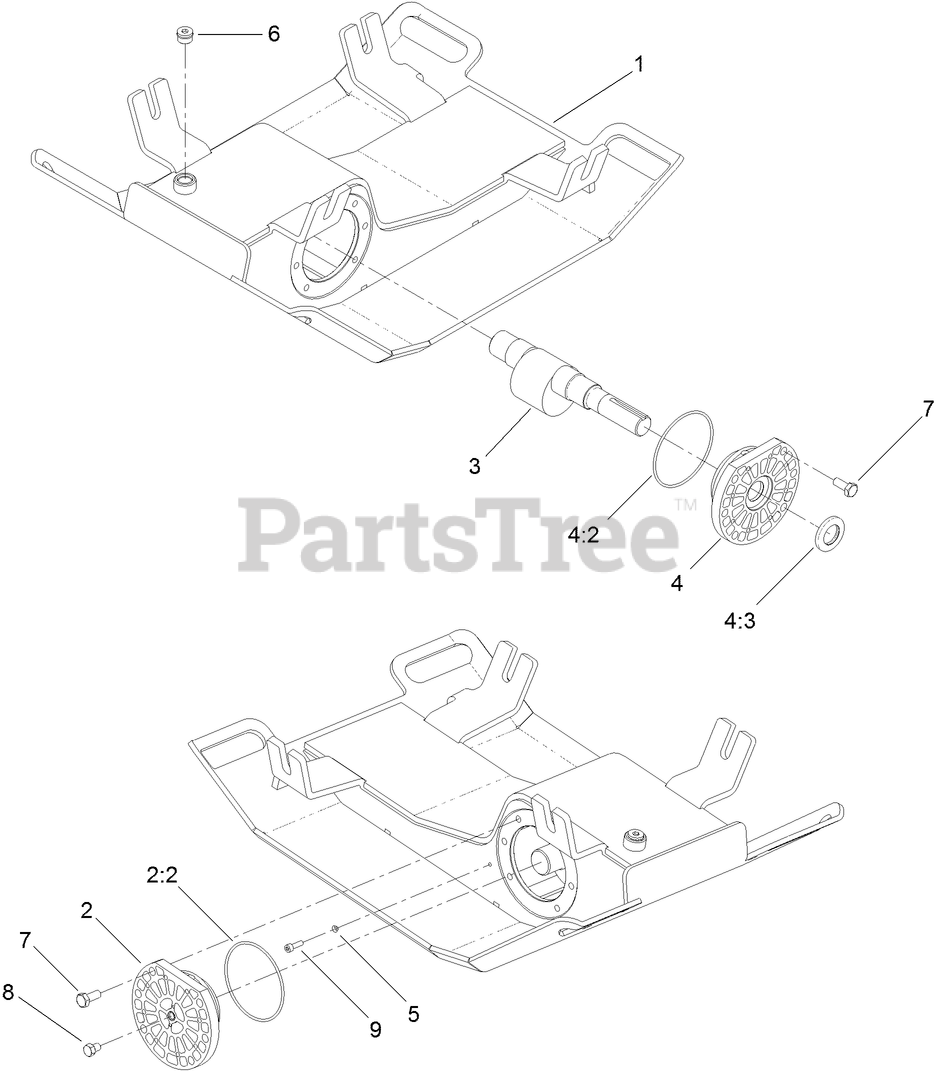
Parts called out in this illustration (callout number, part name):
2	PLATE CAP BEARING ASM
2:2	O-RING
3	SHAFT-ECCENTRIC
4	PLATE CAP BEARING ASM
4:2	O-RING
4:3	SEAL-SHAFT
5	WASHER-SEALING, NYLTITE
6	FITTING-HYD
7	SCREW-HH
8	SCREW-HH
